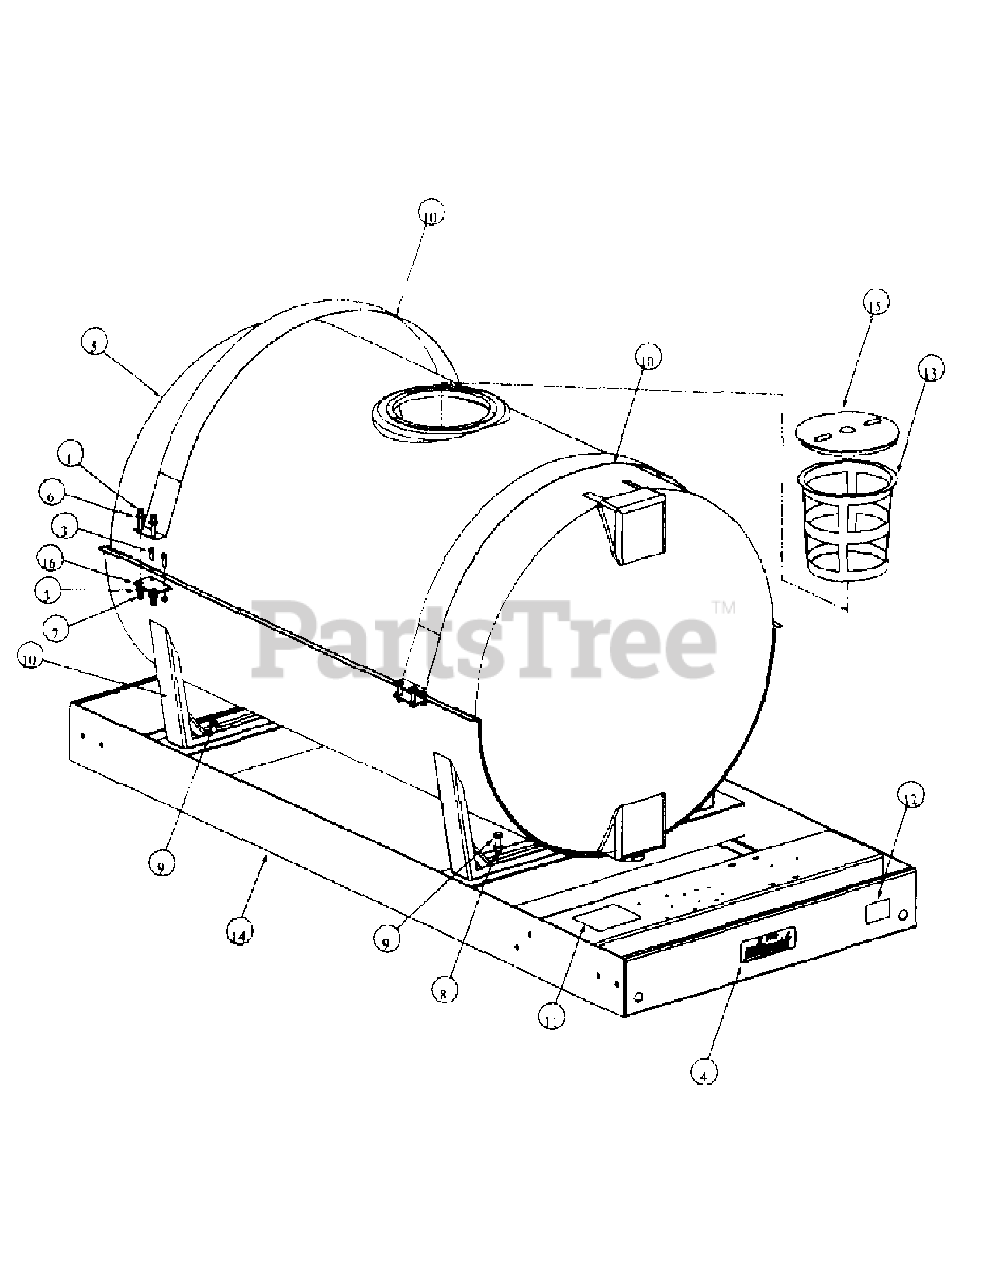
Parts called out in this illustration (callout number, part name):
1	HHCS: 3/8-16, 2.00, Standard
1	HHCS, 3/8-16 x 1"
3	Adhesive Back Foam, 1/4, (sold by ft.)
4	Decal, "Sprayer 300PE", 2-1/4" x 7"
4	Decal, "Sprayer 300", 2-1/4" x 7"
5	Assembly Tank, 300 Gal Poly w/lid
6	Flat Washer, 3/8 SAE
7	Lock Nut, Nylon Insert, 3/8-16
8	Lock Nut, Nylon Insert, 1/2-13
9	HHCS, 1/2-13 x 1"
10	Assembly Saddle, 300 Gal Poly, w/strap
11	Decal Safety Procedures
12	Decal, Made in America
13	Strainer Basket 10"
14	Assembly Main Frame, 300 Gal Poly
15	Tank Lid, 10" Threaded
16	Mount Strap, Tank, 300 Gal Poly
